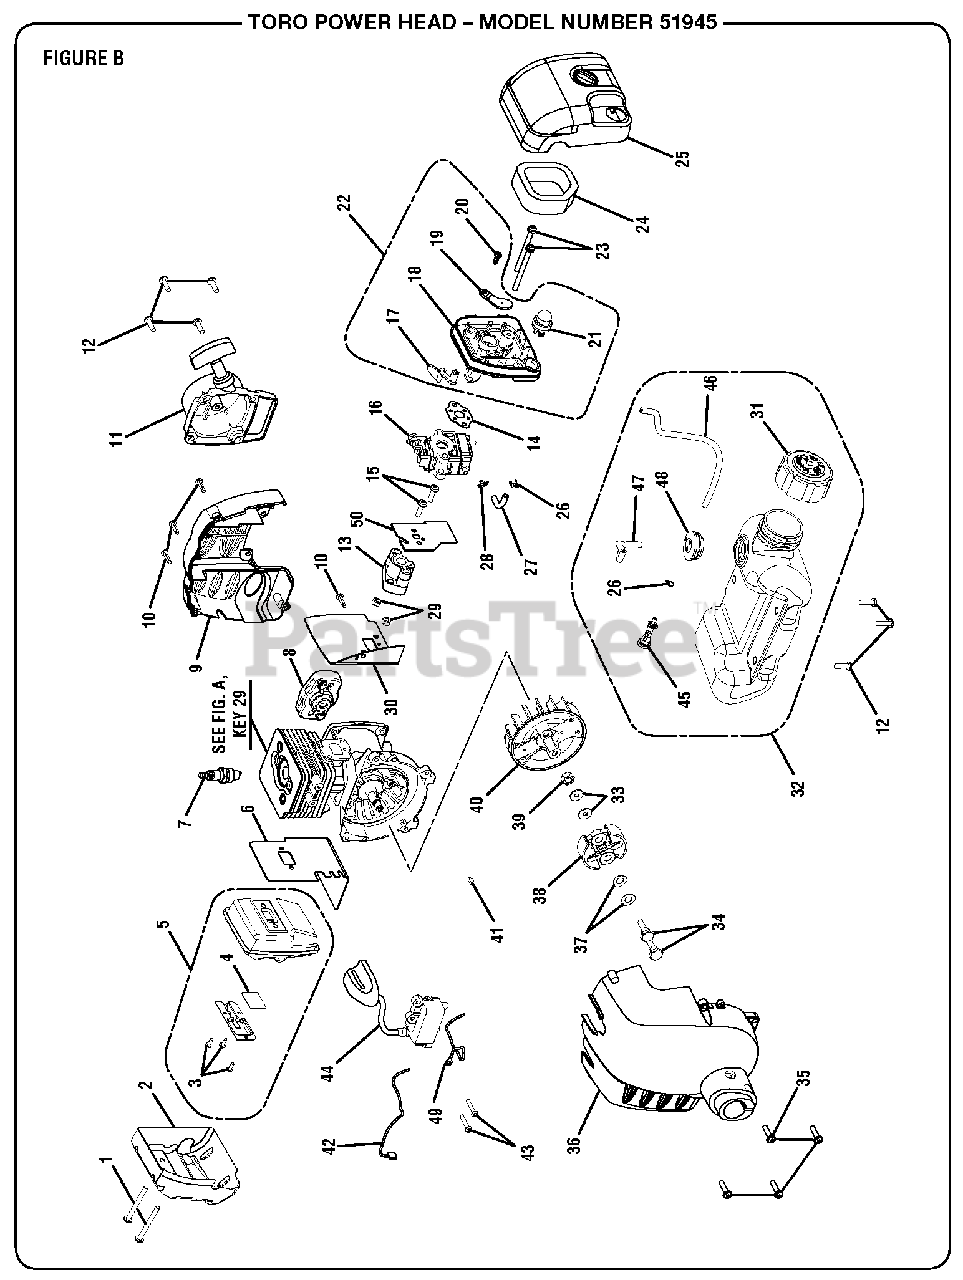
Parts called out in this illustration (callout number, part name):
1	Screw (M5 x 50 mm, Torx Slotted Recessed Pan Hd.)
2	Heat Shield
3	Screw (6-20 x 1/4 in., Pan Hd.)
4	Screen
5	Muffler Assembly
6	Muffler Gasket
7	Spark Plug (RCJ6Y)
8	Starter Cup
9	Rear Engine Housing
10	Screw (M4 x 16 mm, Torx Recessed Pan Hd.)
11	Starter Recoil Assembly
12	Screw (m5 x 16 mm, Torx Slotted)
13	Heat Dam Insulator
14	Carburetor Gasket
15	Screw (M5 x 31 mm, Torx Slotted Recessed Pan Hd.)
16	Carburetor Assembly
17	Choke Lever
18	Carburetor Plate
19	Choke Plate
20	Screw (M4 x 12 mm, Slotted Recessed Pan Hd.)
21	Primer Assembly
22	Filter Housing Assembly
23	Screw (M5 x 60 mm, Slotted Recessed Pan Hd. Machine)
24	Air Filter (Element)
25	Cover Assembly
26	Hose Clip
27	Fuel Line (45 mm)
28	Hose Clip
29	Hex Nut (M5 x .8 mm)
30	Insulator Gasket
31	Fuel Cap Assembly
32	Fuel Tank and Cap Assembly
33	Washer
34	Clutch Screw
35	Screw (M5 x 20 mm, Torx Slotted Recessed Pan Hd.)
36	Front Housing Assembly
37	Curved Washer
38	Clutch Assembly
39	Rotor Nut
41	Woodruff Key (10 mm x 3 mm)
42	Lead Wire (Black)
43	Screw (M4 x 22 mm, Torx Slotted Recessed Pan Hd.)
44	Coil Boot Assembly
45	Fuel Filter
46	Fuel Line (150 mm)
47	Fuel Line (118 mm)
48	Grommet
49	Lead Wire (Red)
